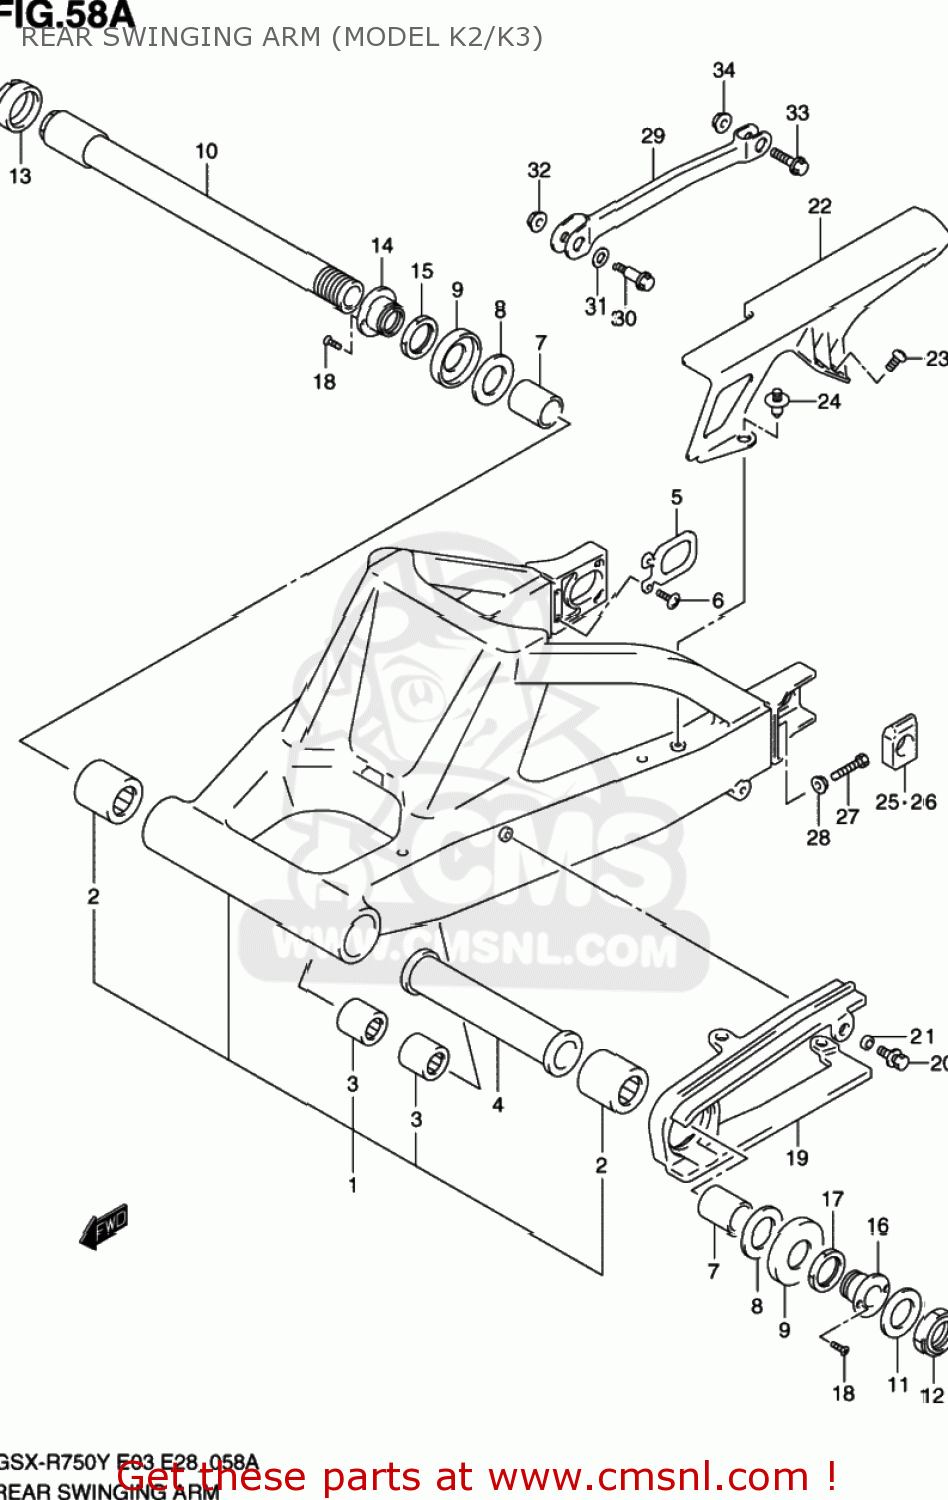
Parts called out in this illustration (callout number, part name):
1	SWINGINGARM ASSY,RR
2	BEARING(30X40X25)
3	BEARING(17X24X20)
4	SPACER,REAR SWING PIVOT,CENTER
5	PLATE,RR SWING ARM BRKT
6	SCREW
7	SPACER,REAR SWING ARM PIVOT
8	WASHER
9	DUST SEAL,RR SWGARM PIVOT
10	SHAFT,RR SWINGINGARM PIVOT
11	WASHER(25.2X42X3.2)
12	NUT
13	NUT,RR SWGARM PIVOT BOLT
14	BOSS,RR SWINGINGARM PIVOT,R
15	NUT,RR SWGARM PIVOT BOSS,R
16	BOSS,RR SWINGINGARM PIVOT,L
17	NUT,RR SWGARM PIVOT BOSS,L
18	SCREW
19	BUFFER,CHAIN TOUCH DEFENSE
20	BOLT(6X20)
21	SPACER(6.5X9X5)
22	CASE,CHAIN
23	SCREW(6X16)
24	CLIP(BLACK)
25	ADJUSTER,CHAIN,R
26	ADJUSTER,CHAIN,L
27	BOLT(8X50)
28	NUT
29	TORQUELINK,RR
30	BOLT(8X34.5)
31	WASHER(12.5X20X1)
32	NUT
33	BOLT(10X37)
34	NUT
